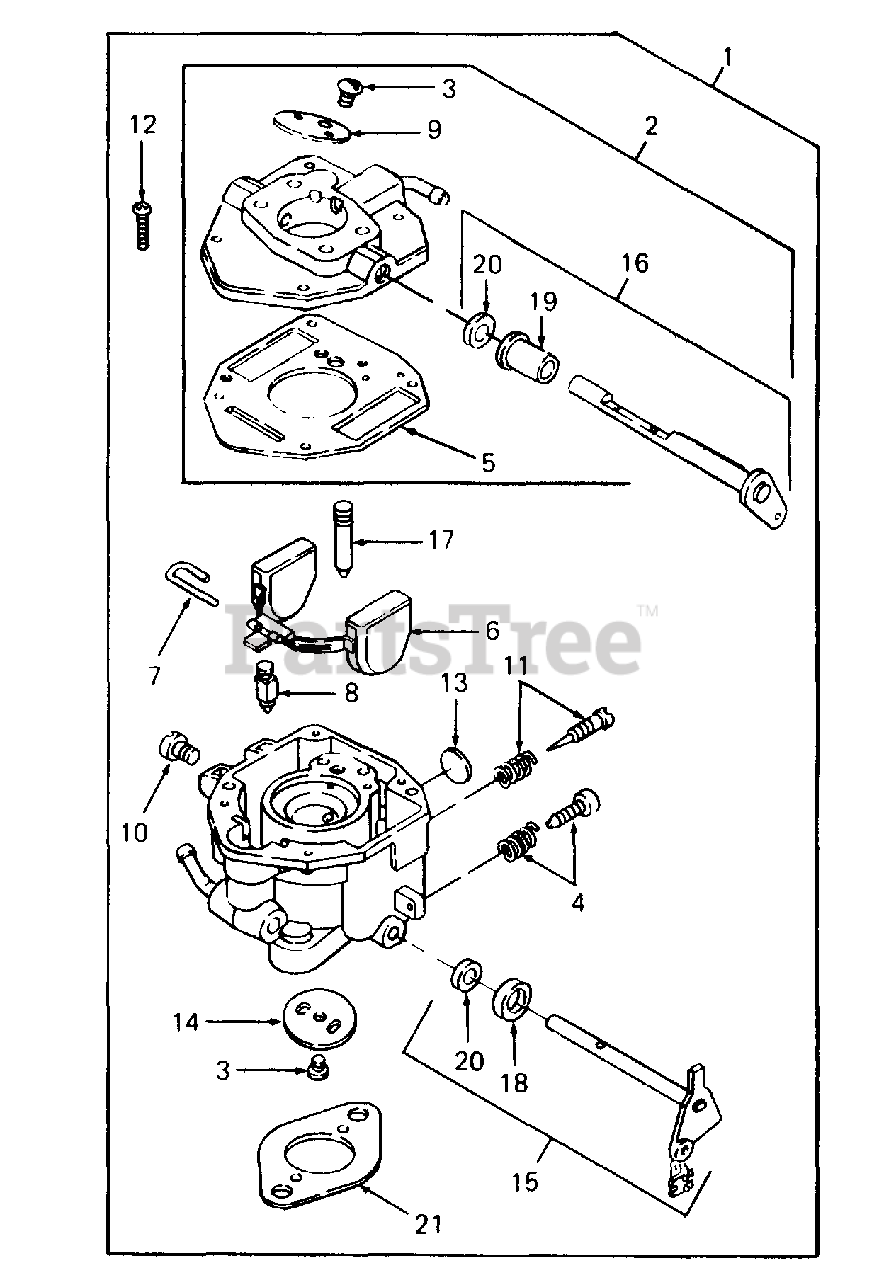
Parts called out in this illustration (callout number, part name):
1	Carburetor Assy
2	Body, Upper Carburetor
3	Screw, Valve Mounting
4	Screw, Throttle Adjustment
5	Gasket, Intake Elbow
6	Float Assy
7	Pin, Float Hinge
8	Valve, Fuel Inlet
9	Valve, Choke
10	Jet, Main
11	Valve, Idle Adjusting Needle
12	Screw, Upper Body Mounting
13	Plug, Welch
14	Valve, Throttle
15	Shaft, Throttle
16	Shaft, Choke
17	Jet, Slow Speed
18	Collar, Throttle
19	Collar, Choke
20	Seal, Shaft
21	Gasket, Carburetor Mounting
